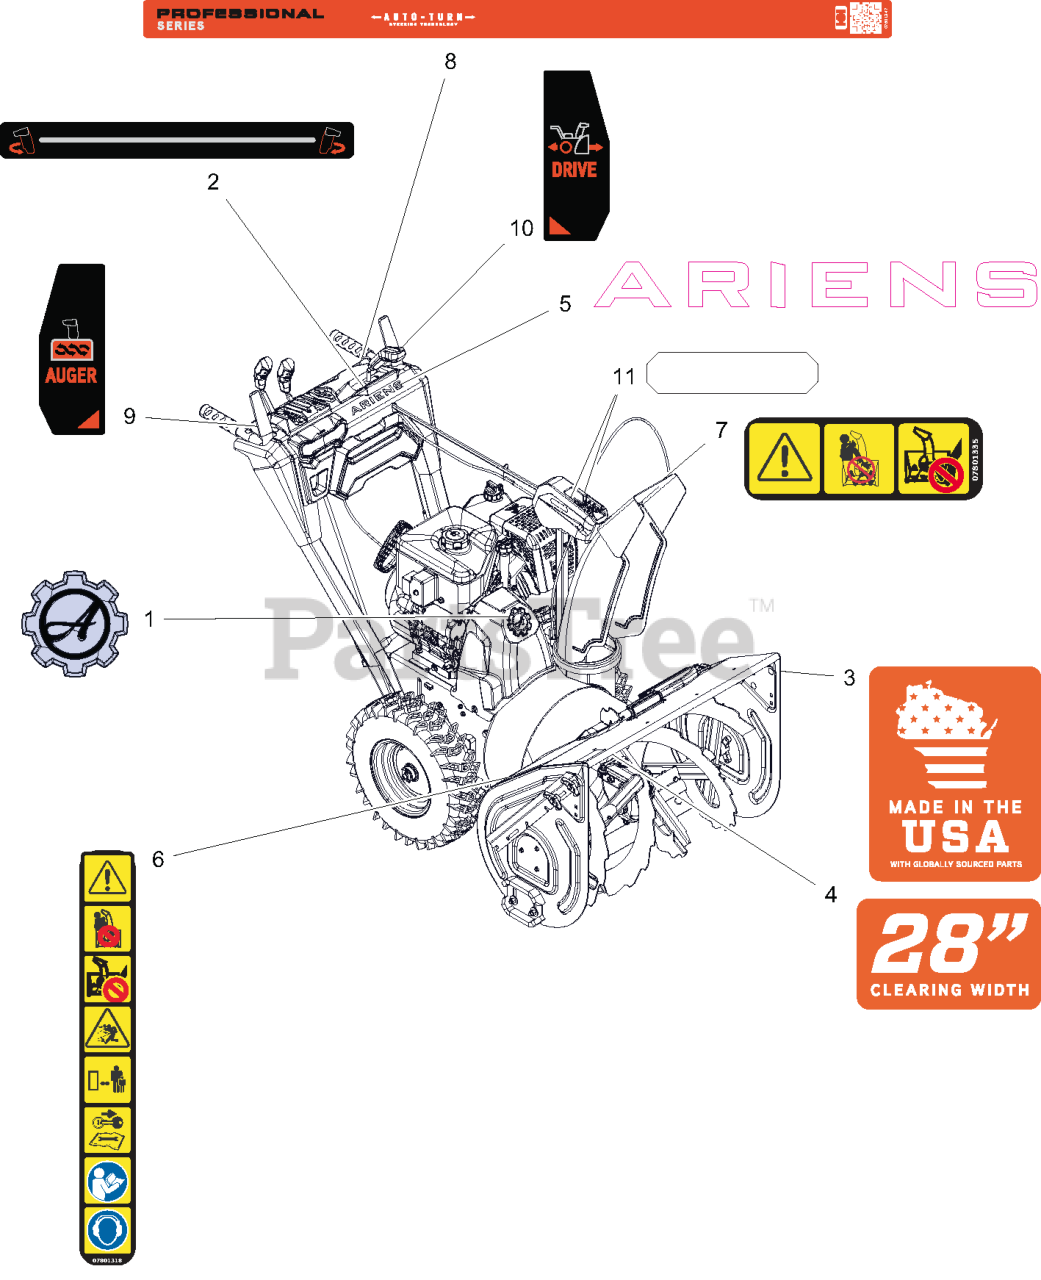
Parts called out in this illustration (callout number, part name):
1	DECAL, ARIENS - GEAR BADGE
2	DECAL- CHUTE ROTATION
3	DECAL- MADE IN USA
4	DECAL- CLEARING - 28
5	DECAL- ARIENS - 7.46"
6	DECAL- SAFETY - DANGER
7	DECAL- DANGER
8	DECAL- DASH - PRO
9	DECAL- CONTROL - AUGER
10	DECAL- CONTROL - DRIVE WHEEL
11	DECAL,REFLECTIVE,GEAR COVER
